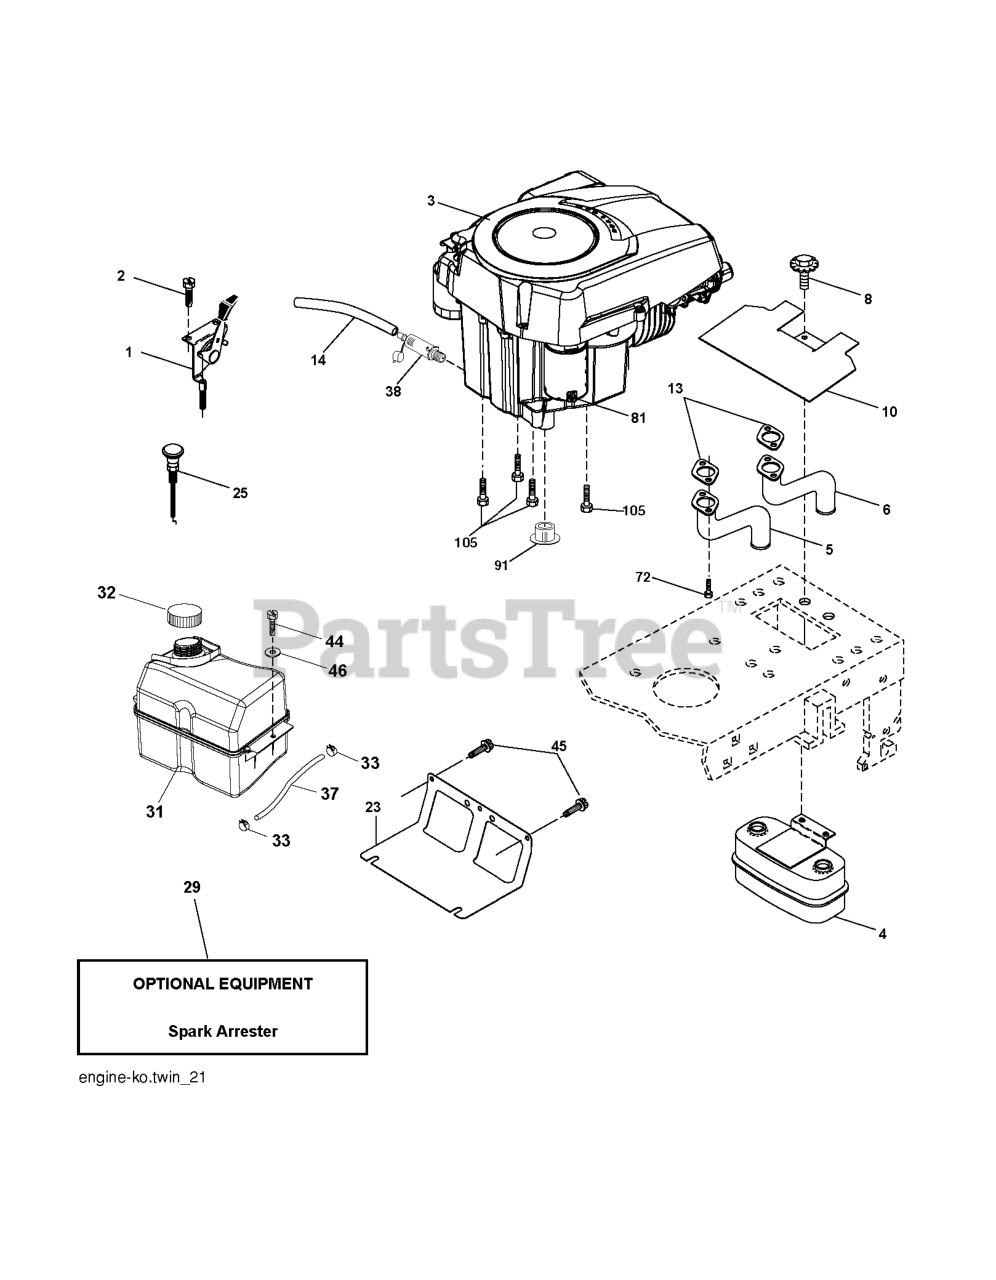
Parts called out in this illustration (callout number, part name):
1	THROTTLE CONTROL
2	SCREW
4	MUFFLER.TWIN.CYL.LOW.TONE
5	RP.PIPE-EXHAUST LH
6	RP.PIPE-EXHAUST RH
8	BOLT.5/16-18UNCX3/4 W/SEMS.BLK
10	RP SHIELD HEAT MUFFLER
13	GASKET.EXHAUST.KOHL.CV18-CV26
14	TUBE, DRAIN OIL ASM.
23	SHIELD.BROWNING.DBR.GUARD
25	CONTROL, CHOKE
29	KIT.SPARK ARRESTOR 794945 B&S
31	TANK.ASM.FUEL.FR.2.5GA.
32	FUEL CAP
33	HOSE CLAMP
37	LINE.FUEL.20
38	PLUG DRAIN OIL EASY
44	SCREW HEXWSHR 1/4-20X3/4
45	SCREW, 3/8-16X3/4
72	SCREW.SOCKET HD.5/16-1
81	NUT
91	BUSHING.1.375OD
105	SCREW 3/8-16X1
